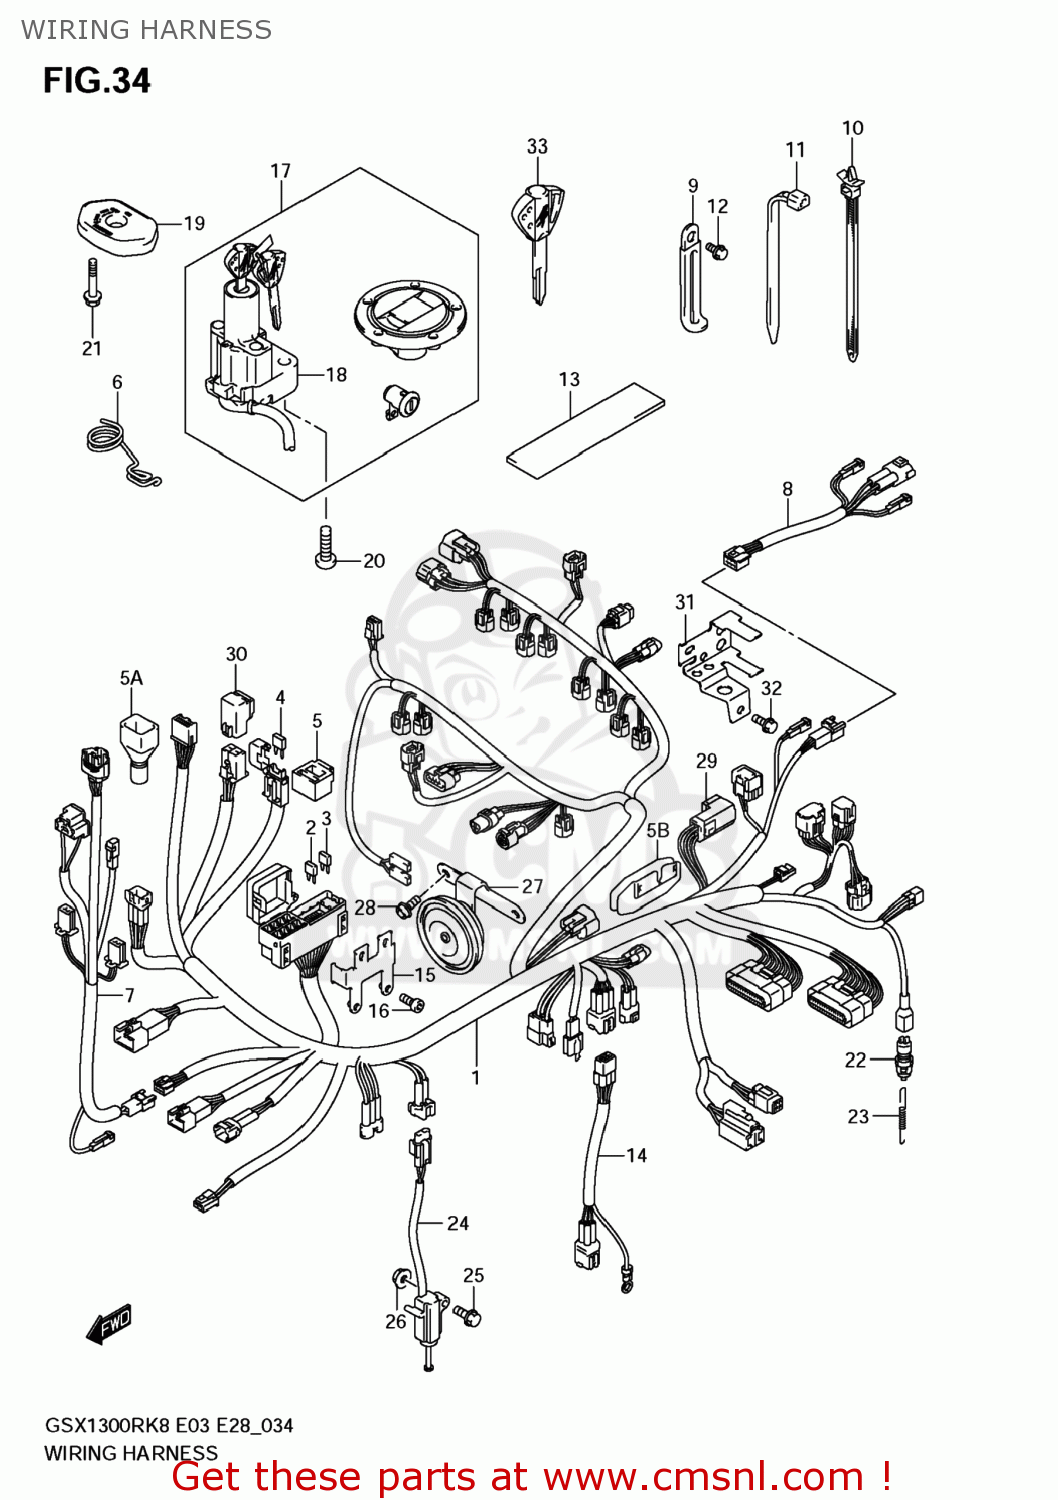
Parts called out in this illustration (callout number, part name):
1	HARNESS,WIRING
2	FUSE(10A)
3	FUSE(15A)
4	FUSE(15A)
5	HOLDER,FUSE
5A	COVER,SPEEDOMETER COUPLER
5B	PROTECTOR,WIRING HARNESS
6	GUIDE,WIRING HARNESS
7	HARNESS,WIRING NO.2
8	WIRE,RR COMB
9	CLAMP(L:45)
10	CLAMP(L:120)
11	CLAMP(L:125)
12	BOLT
13	PROTECTOR,WIRING HARNESS
14	WIRE,O2 SENSOR
15	BRACKET,FUSE BOX
16	BOLT
17	LOCK SET
18	LOCK ASSY,STEERING
19	COVER,STEERING LOCK
20	BOLT(8X20)
21	BOLT
22	SWITCH ASSY,STOP LAMP
23	SPRING
24	SWITCH ASSY,SIDE STAND
25	BOLT(8X35)
26	NUT
27	HORN ASSY
28	BOLT
29	RELAY ASSY
30	RELAY ASSY
31	BRACKET,FUEL PUMP RLY
32	BOLT
33	KEY,BLANK
